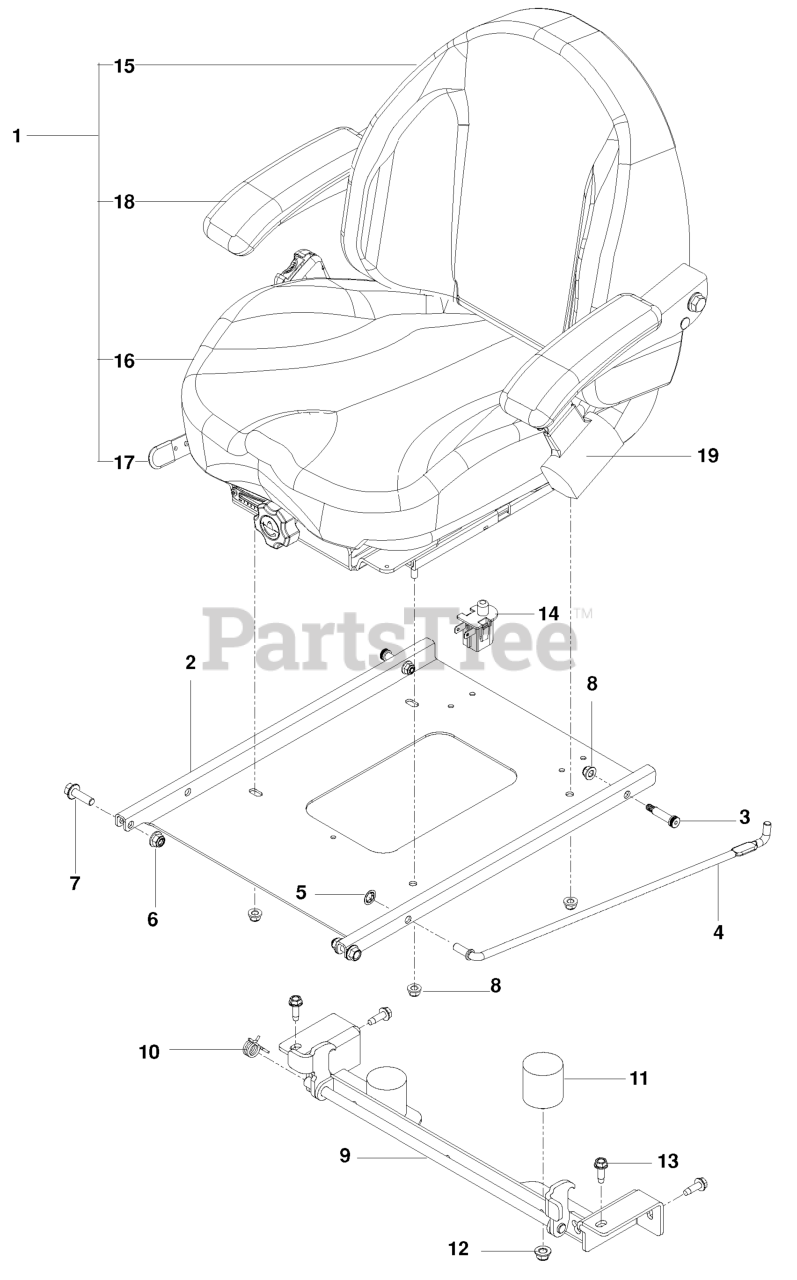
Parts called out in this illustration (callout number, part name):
1	Seat Assy
2	PAN, SEAT, BLACK
3	BOLT, SHOULDER 3/8 X 1.25
4	ROD, SEAT
5	NUT 3/8 PALNUT RTNG BLK PHOS
6	NUT 3/8-16 HEX FLG NYLOC ZD
7	HHFS 3/8-16 X 1.25 GD 5
8	5/16-18 NYLOC FLANGE NUT
9	LATCH.SEAT.BLACK
10	SPRING, TORSION
11	BUMPER, RUBBER
12	NUT 3/8-16 HEX FLG NYLOC ZD
13	RP BLT 5/16-18 X 1 THRD FORM D
14	SEAT SWITCH
15	COVER, BACK
16	COVER KIT, CUSHION
18	ARMREST, LT
19	Seat Belt
